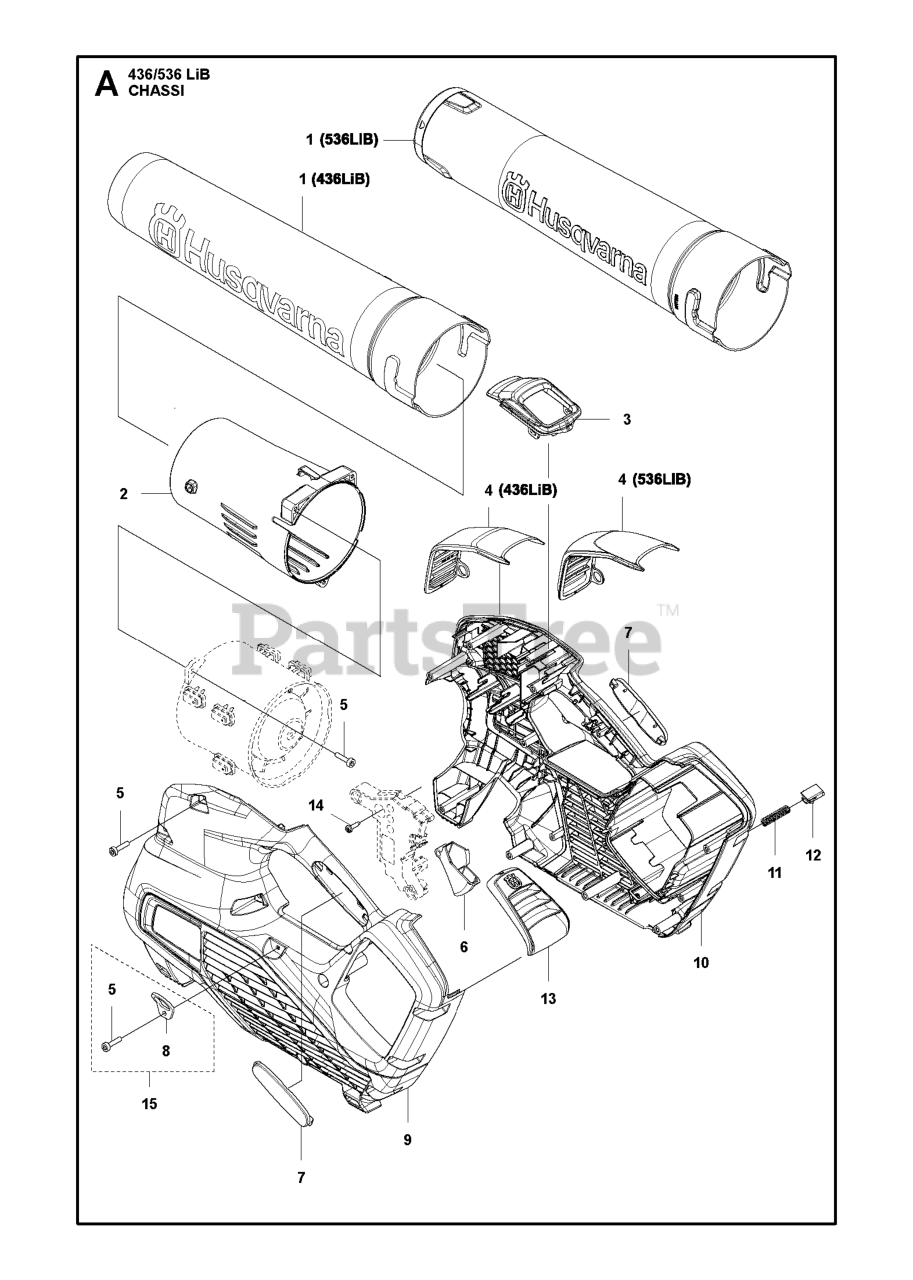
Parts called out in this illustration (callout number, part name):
1	NOZZLE 436LIB
1	TUBE ASSY
2	TUBE FAN OUTLET
3	FRAME KEYPAD
4	COVER
5	SCREW
6	THROTTLE CONTROL
7	HANDLE INSERT GREY
8	EYELET
9	HOUSING LEFT B1
10	HOUSING RIGHT B1
11	SPRING PUSH OUT
12	PUSH BUTTON
15	KIT EYELET
